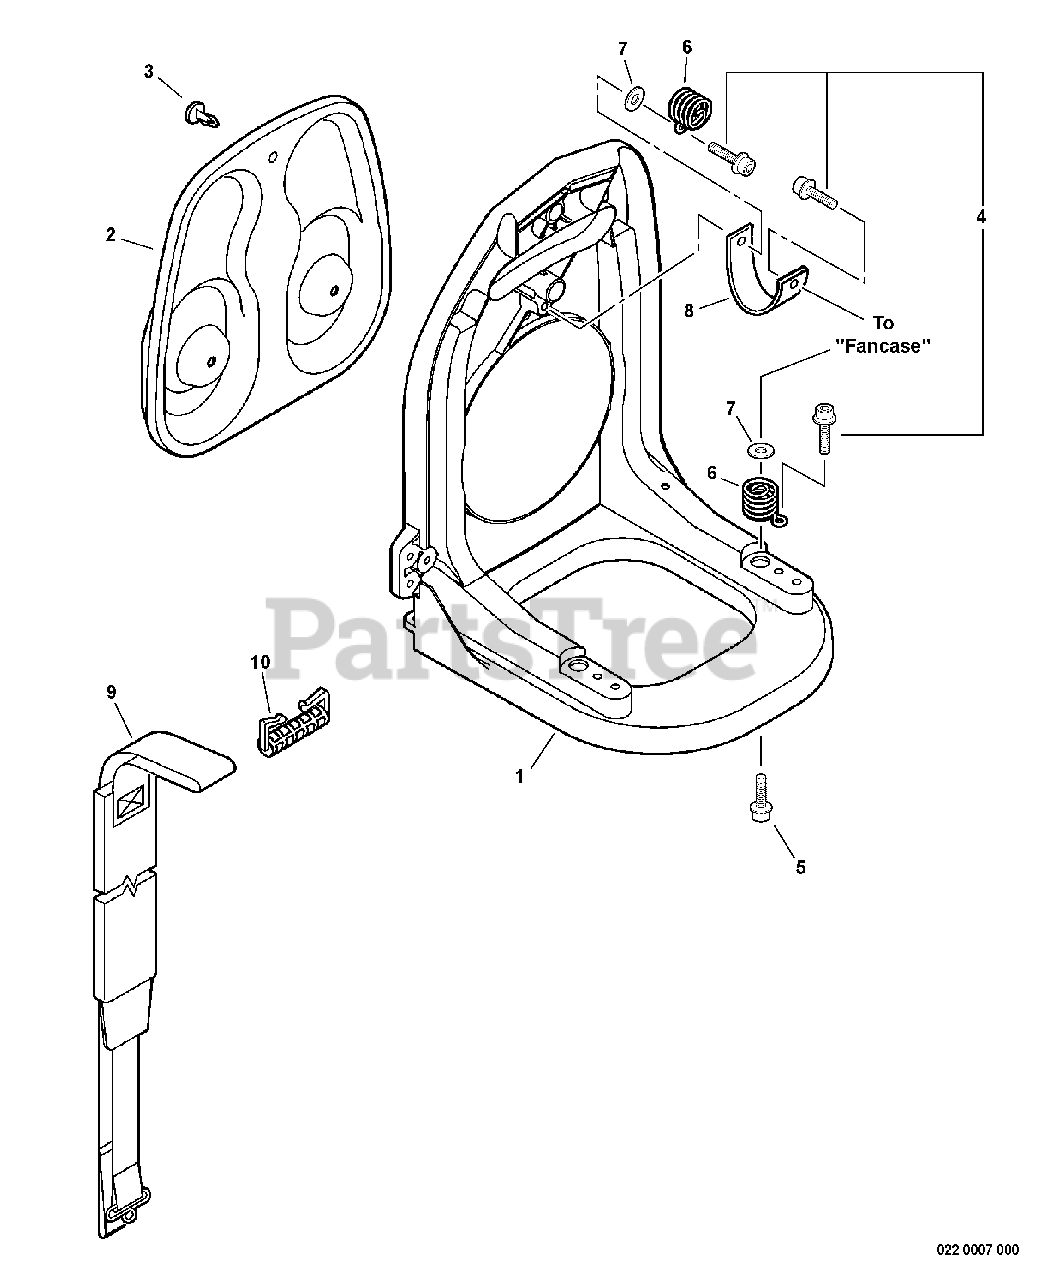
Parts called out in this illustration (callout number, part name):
1	FRAME, BACKPACK
2	CUSHION, BACKPACK
4	SCREW - 5X20
5	SCREW - 5X14
7	WASHER - 5
8	STRAP, SAFETY
9	BACKPACK STRAP ASSY
10	RETAINER, HARNESS
